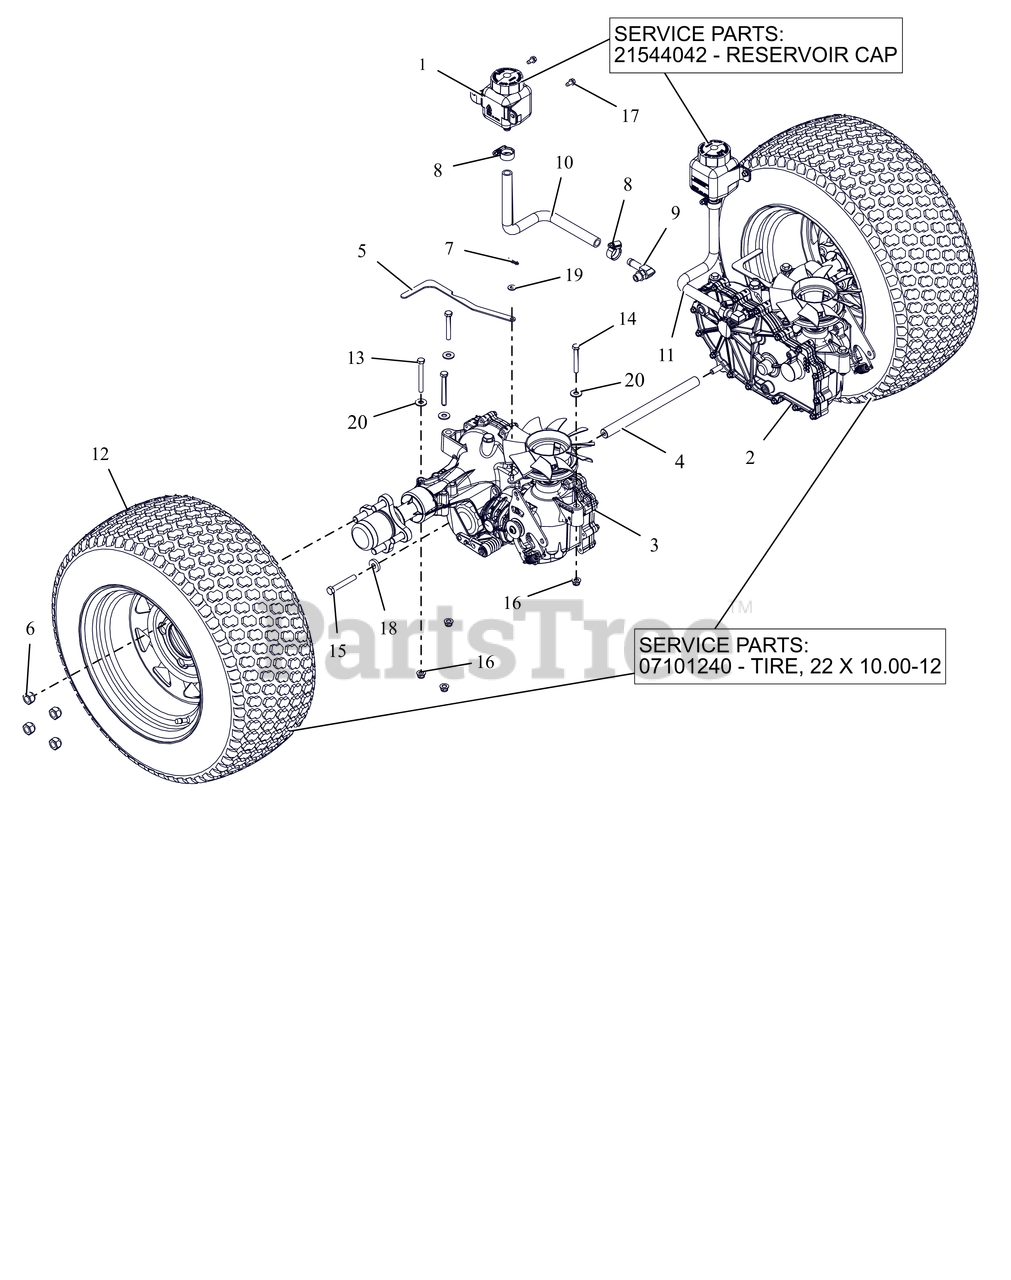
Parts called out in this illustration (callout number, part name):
1	TANK, EXPANSION
1	CAP, HYDRO RESERVOIR REPLAC.
2	TRANSAXLE, ZT3100 LH
3	TRANSAXLE, ZT3100 RH
4	SHAFT, TRANSAXLE SUPPORT
5	BRKT, VALVE DUMP
6	WHEEL NUT .500-20 YZ
7	PIN-HAIR, ENDRIES #25 YWZC
8	CLAMP,.88 DIA. HOSE
9	FITTING, HYD (90 DEG)
10	HOSE, FORMED EXPANSION -HD RH
11	HOSE, FORMED EXPANSION -HD LH
12	ASM, WHL/TIRE 22X10.00-12 K500
12	TIRE, 22X10.00-12
13	@BLT-HEX .31-18X2.75 GR5 YWZC
14	@BLT-HEX .31-18X2.25 GR5 YWZC
15	@BLT-HEX .38-16X2.50 GR5 YWZC
16	@NUT-LK-NYL-FLG .31-18 YWZC
17	SCR-TAP .25-20X.50 HWH TR YWZ
18	WSHR-FL-STL .406X1.00X.188 YWZ
19	@WSHR-FL-STL.281X.62X.065 YWZC
20	@WSHR-FL-STL.38X.875X.083 YWZC
